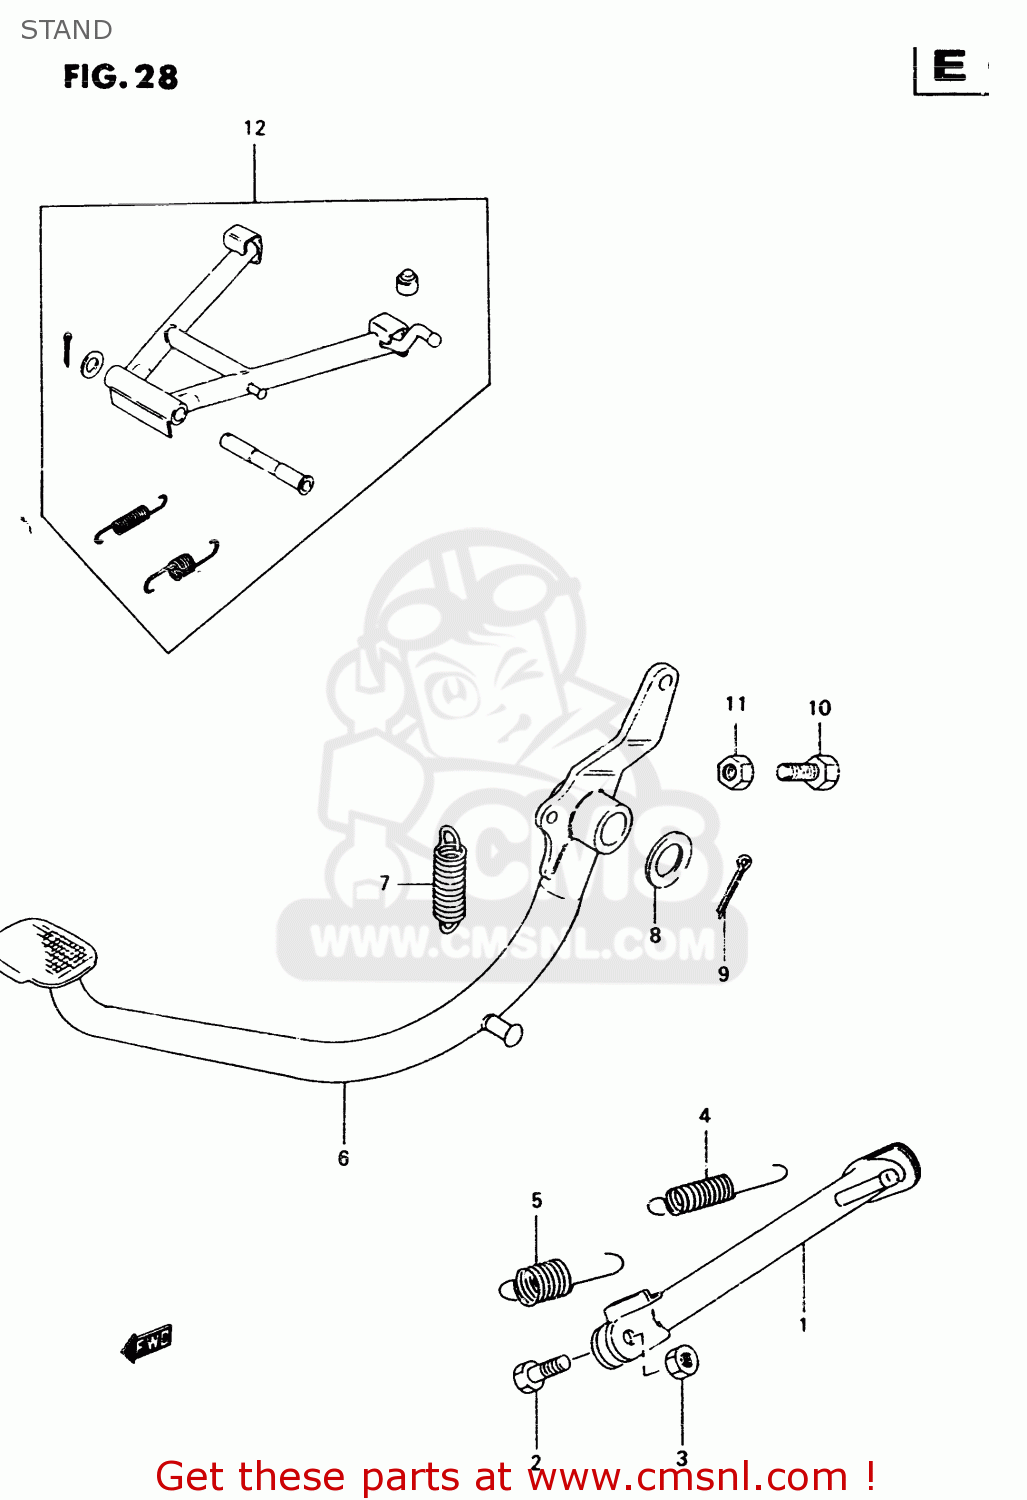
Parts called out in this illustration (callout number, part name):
1	STAND,PROP
2	BOLT(10X34)
3	NUT
4	SPRING
5	SPRING
6	PEDAL,BRAKE
7	SPRING
8	WASHER(15.5X26X2.3)
9	COTTER PIN
10	BOLT(6X23)
11	NUT 6MM
12	STAND ASSY,CTR
